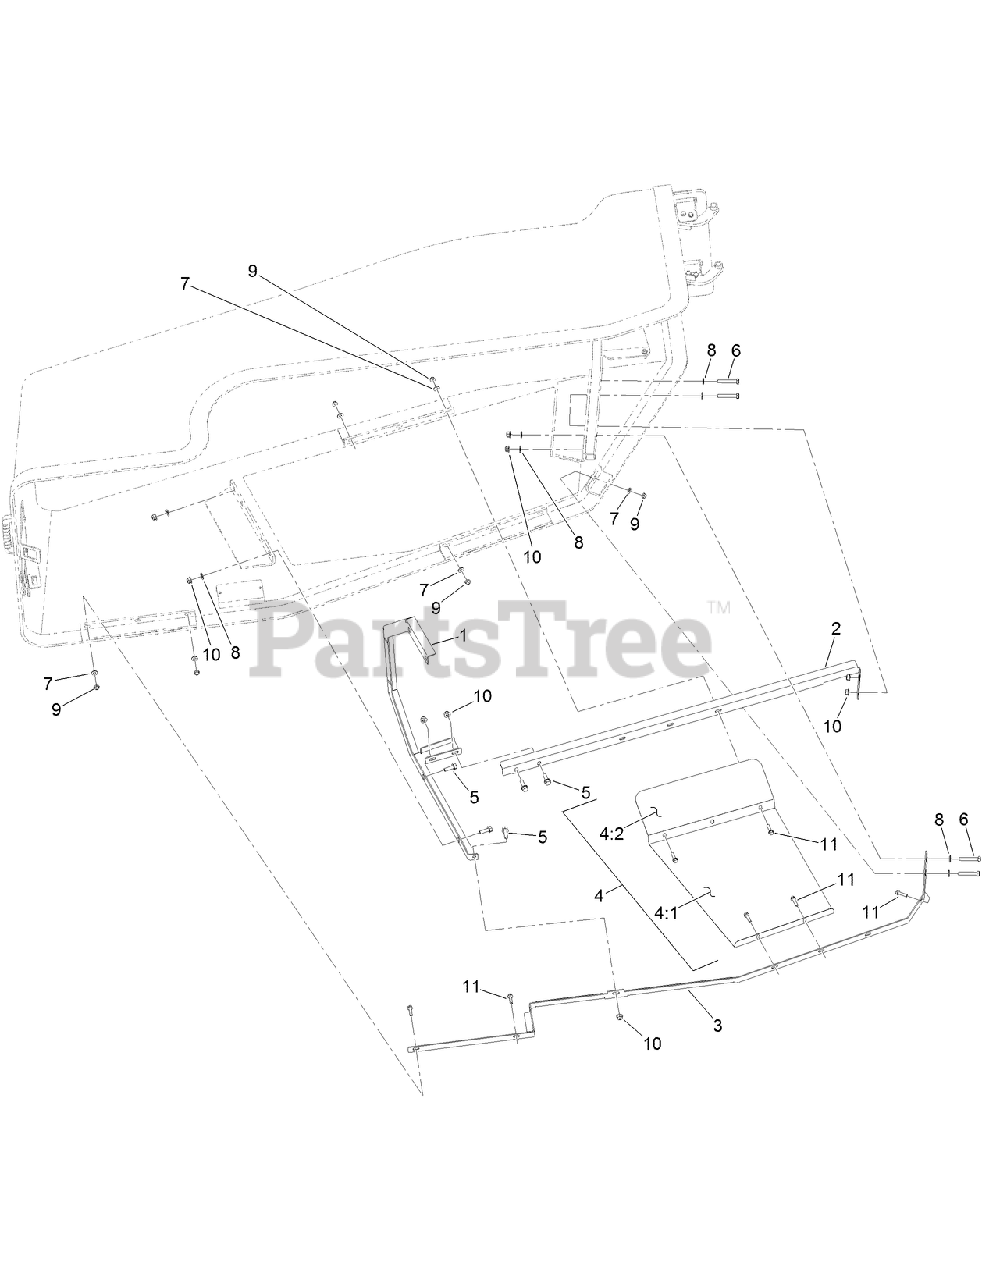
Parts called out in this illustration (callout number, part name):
1	CHANNEL-SUPPORT
2	SUPPORT-HOOD, UPPER
3	SUPPORT-EDGE, FRONT
4	FRONT HOOD HEAT GUARD ASM
4:1	SHIELDING-HEAT, LOWER GUARD
4:2	SHIELDING-HEAT, UPPER GUARD
5	SCREW-HHF
6	SCREW-HH
7	WASHER-FLAT
8	WASHER-PLAIN
9	NUT-HF
10	NUT-HF, NI
11	SCREW-HHF
